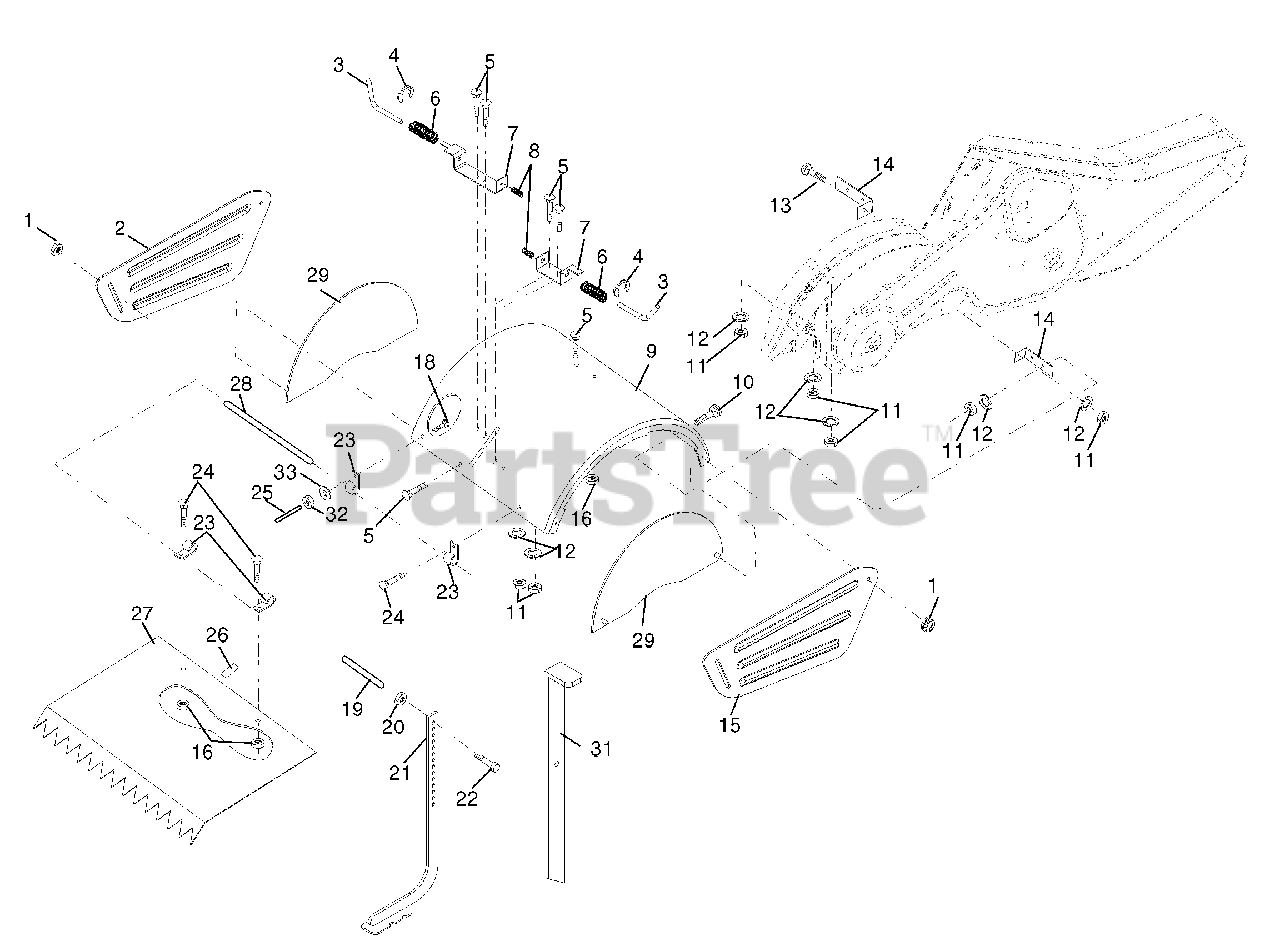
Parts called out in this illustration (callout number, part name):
1	Nut, Lock Hex Flange 5/16-18 unc
2	Shield, Side, Outer L. H.
3	Pin, Stake, Depth
4	Ring, Klip
5	Bolt Rdhd Sqnk 5/16-18 x 3/4
7	Bracket, Latch
8	Spring, Depth Stake
9	Shield, Tine
10	Bolt 5/16-18 x 1
11	Washer, Lock 5/16
12	Nut, Hex 5/16-18
13	Bolt, Carriage 5/16-18 x 1-1/4
14	Bracket, Shield Tine
15	Shield, Side, Outer R.H.
16	Nut, Hex Flange 1/4-20
18	Bolt, Carriage 1/4-20 x 1-1/4 Gr. 5
20	Nut, Hex 3/8-16
21	Stake, Depth
22	Bolt, Hex 3/8-16 x 2
24	Bolt, Carriage 1/4-20 x 1/2
25	Cap, Vinyl
26	Pad, Idler
27	Shield, Leveling
28	Pin, Hinge
29	Shield, Side
31	Stake, Drag
32	Nut, Fin, Hex 1/4-20 unc
33	Washer Lock Hvy Helical 1/4
